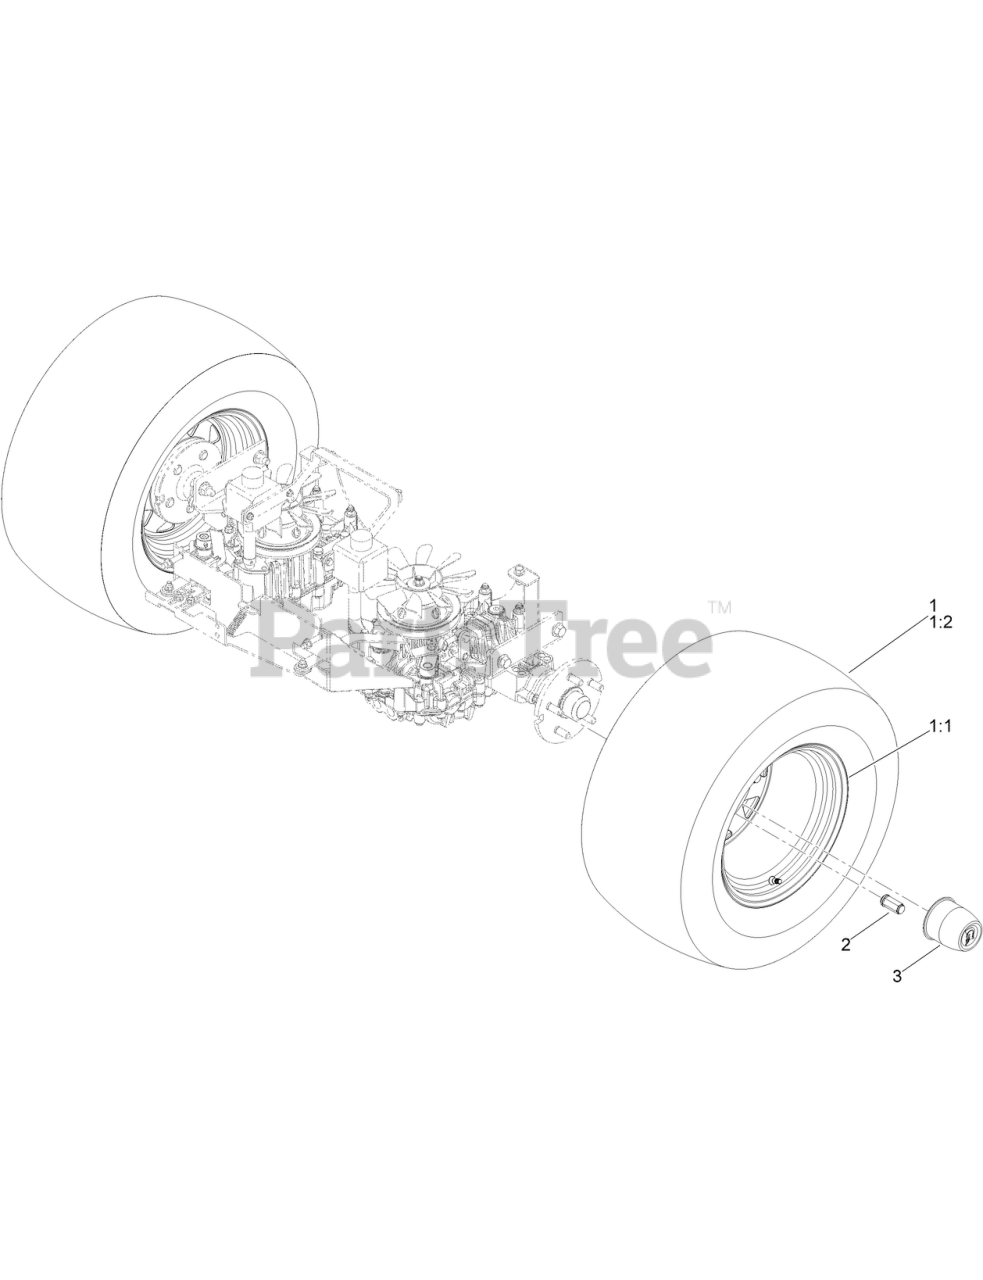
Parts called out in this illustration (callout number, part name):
1	TURF ARMOR 24X12-12 RR TIRE/WHEEL ASSY
2	LUG NUTS
3	RR STEEL WHEEL SILVER CNTR CAP
